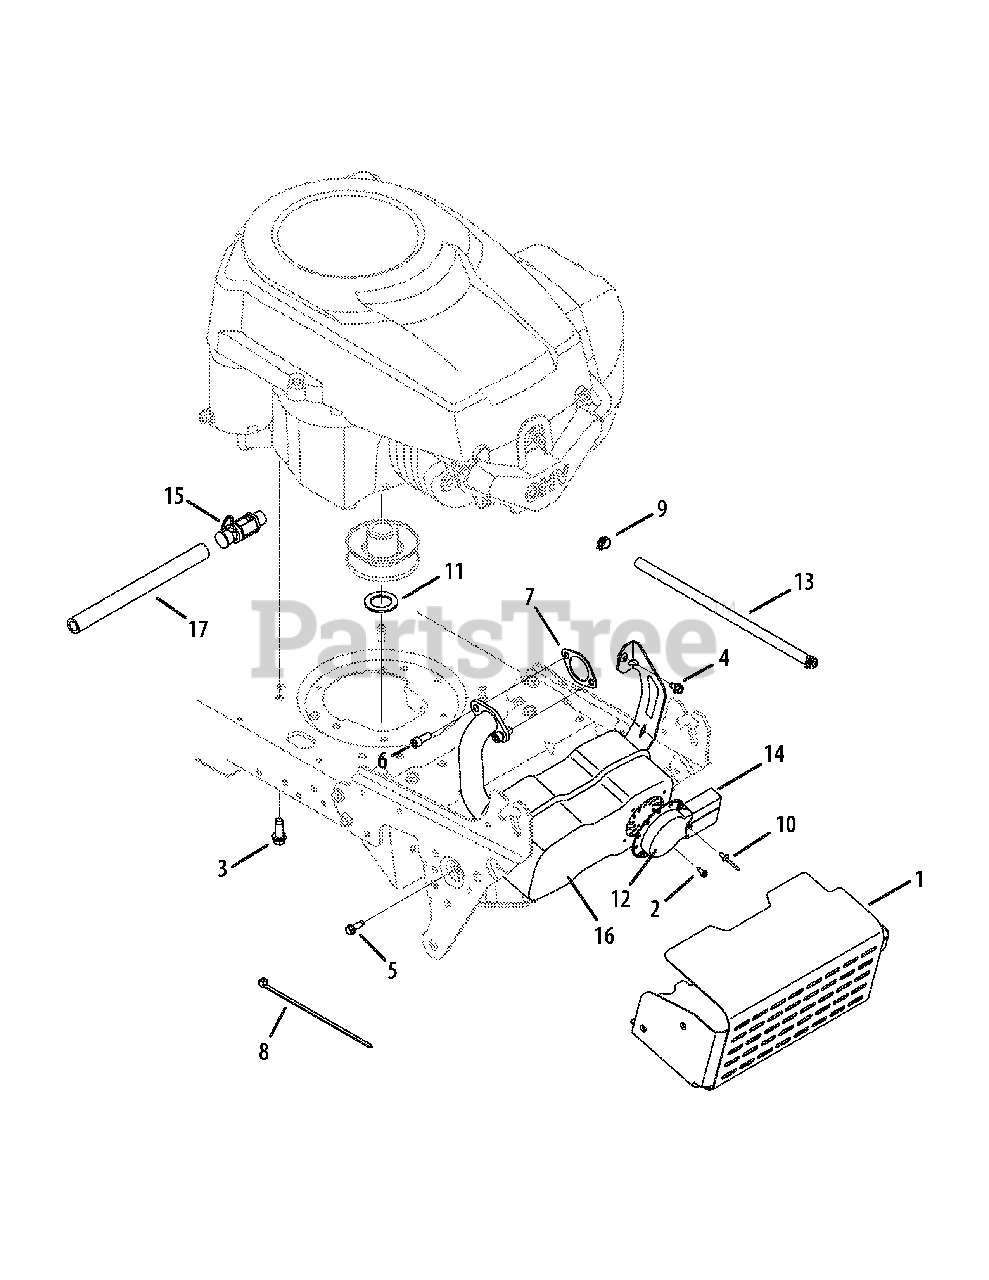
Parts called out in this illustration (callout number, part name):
2	Screw, #8-18, 0.500
3	Screw, Hex, 3/8-16 x 1.00
4	Screw, Hex, 1/4-20, 0.500
5	Screw, Hex, 1/4-20, 0.750
6	Screw, 5/16-18, 0.75
7	Exhaust Gasket
8	Cable, Tie, 3/16 x .05 x 7.4
9	Hose Clamp
10	Rivet, Pop, .188 x .325
11	Flat Washer, 1.031 x 1.620 x .095
12	Deflector, Muffler
13	Fuel Line, Low Permeation
14	Extension, Deflector
15	Drain, Oil
16	Muffler, Single Inlet
17	Extension Hose, Oil Drain
